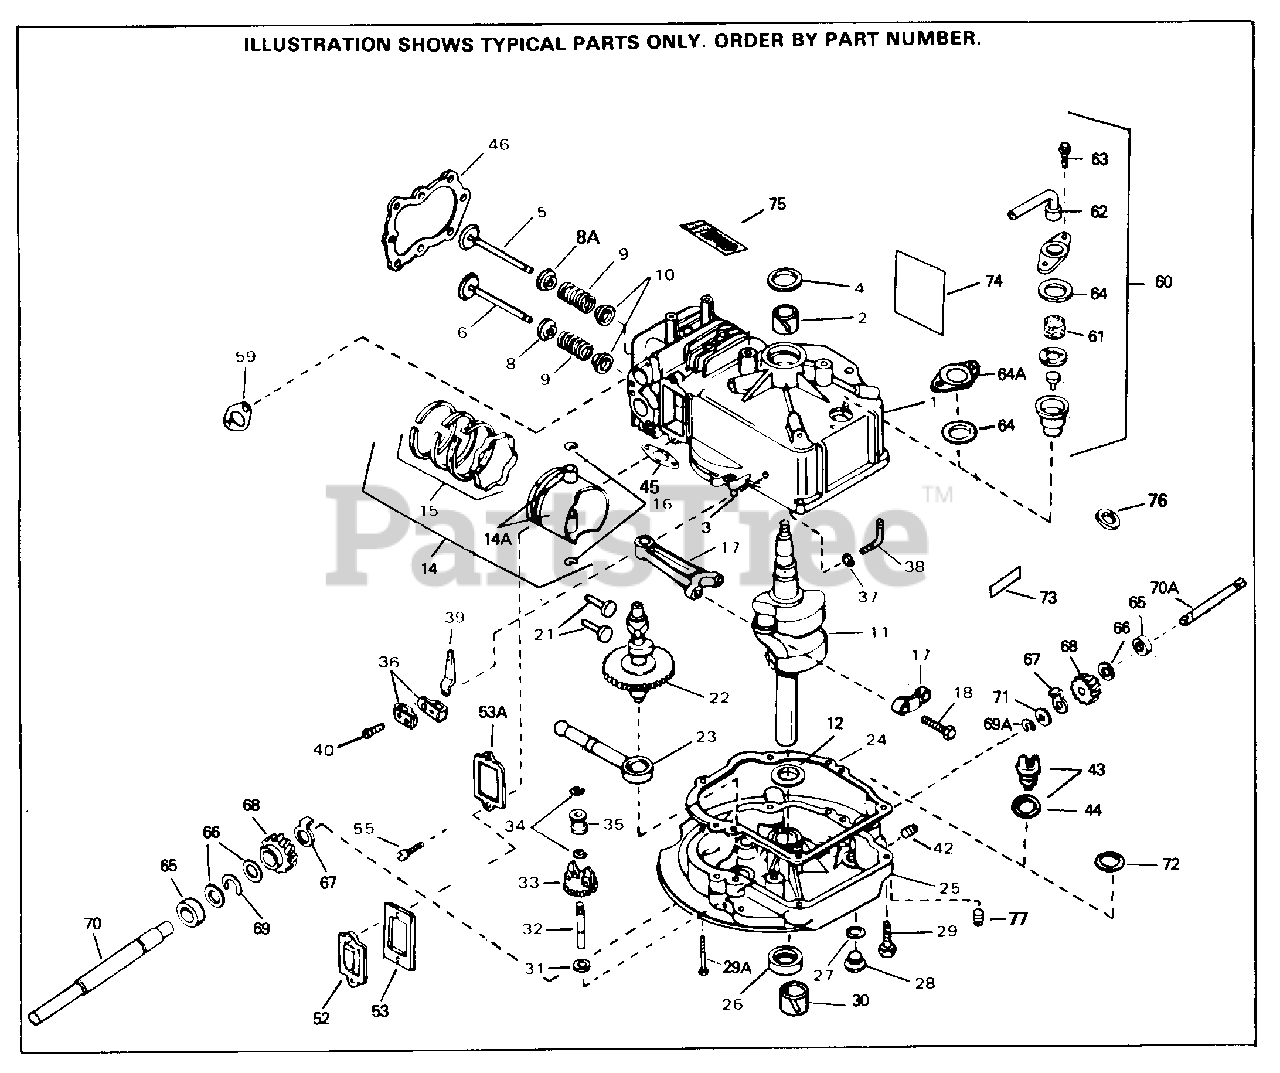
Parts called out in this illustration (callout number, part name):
1	"Cylinder (Incl. 2, 3, 4 & 76) 2-5/8"B ore
2	Bushing, Cylinder
3	Dowel Pin
4	Seal, Oil
5	Intake Valve (Std.) (Incl. 151)
5	Exhaust Valve (1/32" OS) (Incl. 151)
6	Exhaust Valve (Std.) (Incl. 10)
6	Exhaust Valve (1/32" OS) (Incl. 10)
8	Upper Valve Spring Cap Early Prod. On ly
8A	Upper Valve Spring Cap Early Prod. On ly
9	Spring, Valve
10	Cap, Lower valve spring
11	Crankshaft
12	Washer, Thrust
14	Piston, Pin & Ring Set (Std.) 2-5/8"B ore
14	Piston, Pin & Ring Set (.010" OS)
14	Piston, Pin & Ring Set (.020" OS)
14A	Piston & Pin Ass'y. (Incl. 16)(Std.) 2-5/8"
14A	Piston & Pin Ass'y. (Incl. 16) .010"O S
14A	Piston & Pin Ass'y. (Incl. 16) .020"O S
15	Ring Set (Std.) (2-5/8" Bore)
15	Ring Set (.010" OS)
15	Ring Set (.020" OS)
16	Piston Pin Retaining Ring
17	Rod Assy., Connecting (Incl. 18)
18	Bolt, Connecting rod
21	Valve Lifter
22	Camshaft (MCR)
23	Oil Pump Ass'y.
24	Mounting Flange Gasket
25	Mounting Flange Ass'y. Incl. 26, 28& 32
26	Oil Seal
28	Plug, Oil drain
29	Screw, 1/4-20 x 1-1/4"
29A	Screw, 1/4-20 x 1-1/4"
30	Bushing, Flange
31	Washer, Flat
32	Shaft, Mechanical governor
33	Gear Assy., Governor (Incl. 31)
34	Retaining Ring
35	Spool, Governor
36	Clamp, Governor lever
37	Flat Washer
38	Rod, Governor (Incl. 37)
42	Plug, Pipe
45	Exhaust Gasket
46	Gasket, Head
52	Cover, Valve spring box
53	Valve Cover Gasket
55	Screw, 10-24 x 1/2"
59	Gasket, Intake pipe
64	Gasket, Breather
74	Decal, Instruction
75	Decal, Name
76	Washer, S.E. brake
